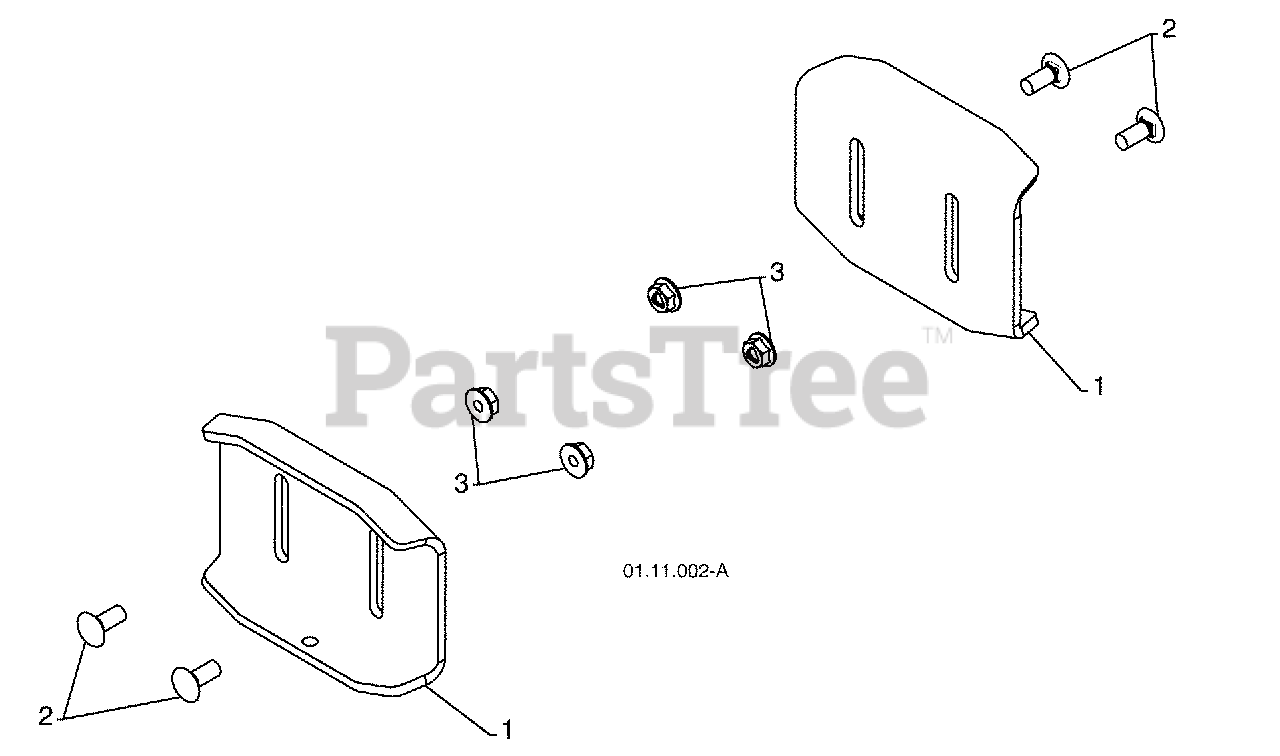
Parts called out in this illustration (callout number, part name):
1	SKID PLATE
2	CARRIAGE BOLT 5/16-18 X .750
3	NUT 5/16-18
